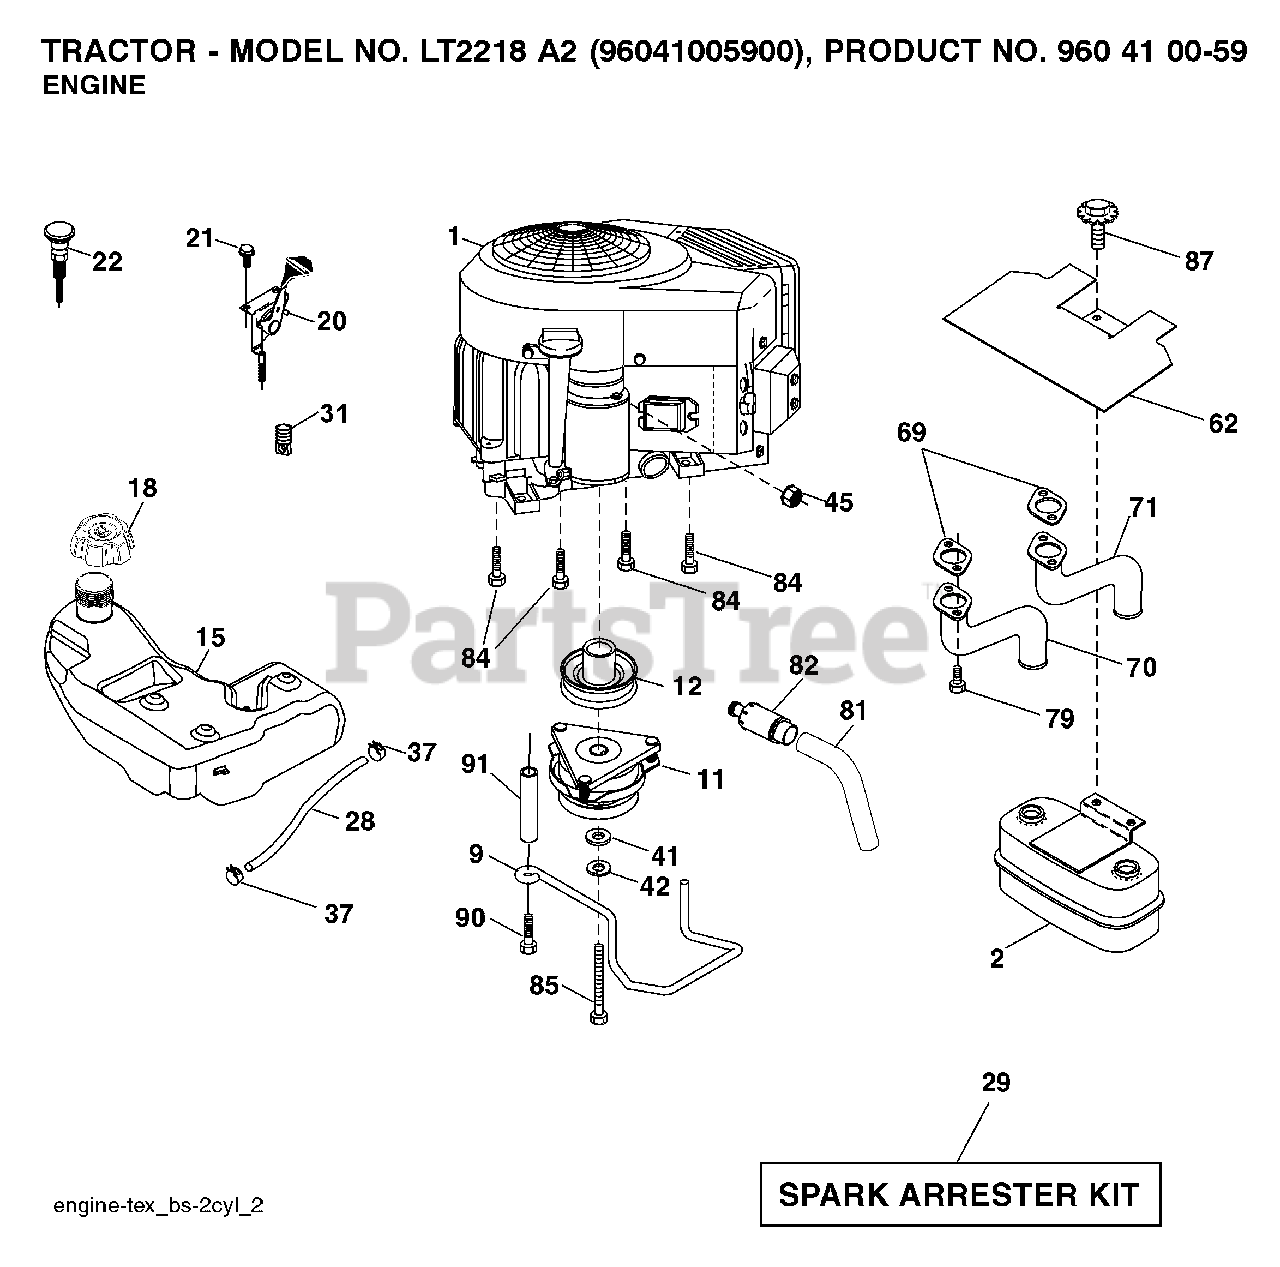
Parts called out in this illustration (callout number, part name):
2	MUFFLER.TWIN.CYL.LOW.TONE
9	KEEPER.BELT.ENGINE.4.2
11	CLUTCH
12	PULLEY.ENGINE.TUFFTORQ
15	TANK.FUEL.4GAL
18	CAP.ASM.FUEL.TANK.3"BL
20	THROTTLE CABLE
21	SCREW
22	CONTROL CHOKE
29	ARRESTER SPARK (OPTIONAL)
31	PUSH CLIP
37	HOSE CLAMP
42	LOCKWASHER
45	NUT
62	RP SHIELD HEAT MUFFLER
69	GASKET.MUFFLER
70	TUBE MANIFOLD LH
71	EXHAUST TUBE RH
79	SCREW.SOCKET.HEAD.5/16-18
81	TUBE, DRAIN OIL ASM.
82	PLUG DRAIN OIL EASY
84	SCREW.3/8-16
85	BOLT HEX 7/16-20X4-1/4"
87	BOLT.5/16-18UNCX1.W/SEMS.BLK
90	SCREW 3/8-16X1
91	BUSHING.1.375OD
